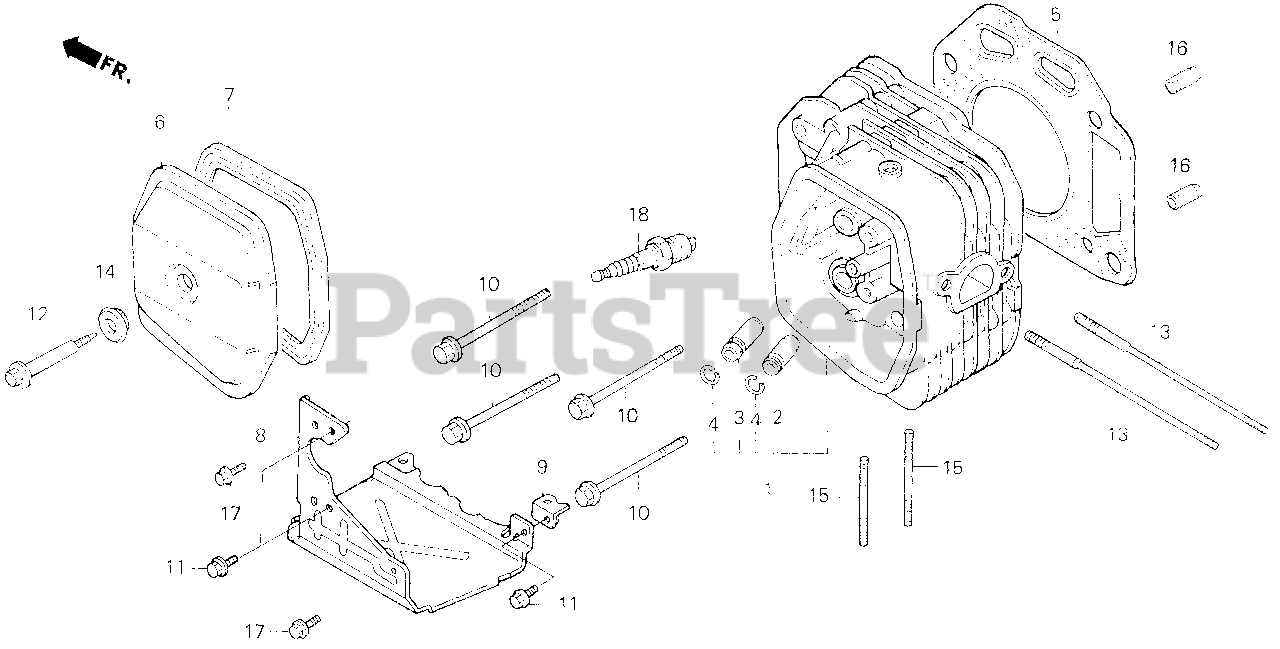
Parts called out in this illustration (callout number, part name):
1	CYLINDER HEAD
2	GUIDE, VALVE (OS)
3	GUIDE, EX. VALVE (OS)
4	CLIP, VALVE GUIDE
5	GASKET, CYLINDER HEAD
6	COVER, HEAD
7	GASKET, CYLINDER HEAD COVER
8	COVER (LOWER)
9	STAY, COVER (LOWER)
10	BOLT, FLANGE (10X85)
11	BOLT, FLANGE (6X12) (CT200)
12	BOLT, HEAD COVER
13	BOLT, STUD (8X131.5)
14	WASHER, HEAD COVER
15	BOLT, STUD (8X32)
16	PIN A, DOWEL (12X20)
17	BOLT, FLANGE (6X12)
18	SPARK PLUG (BPR5ES) (NGK)
18	SPARK PLUG (W16EPR-U) (DENSO)
